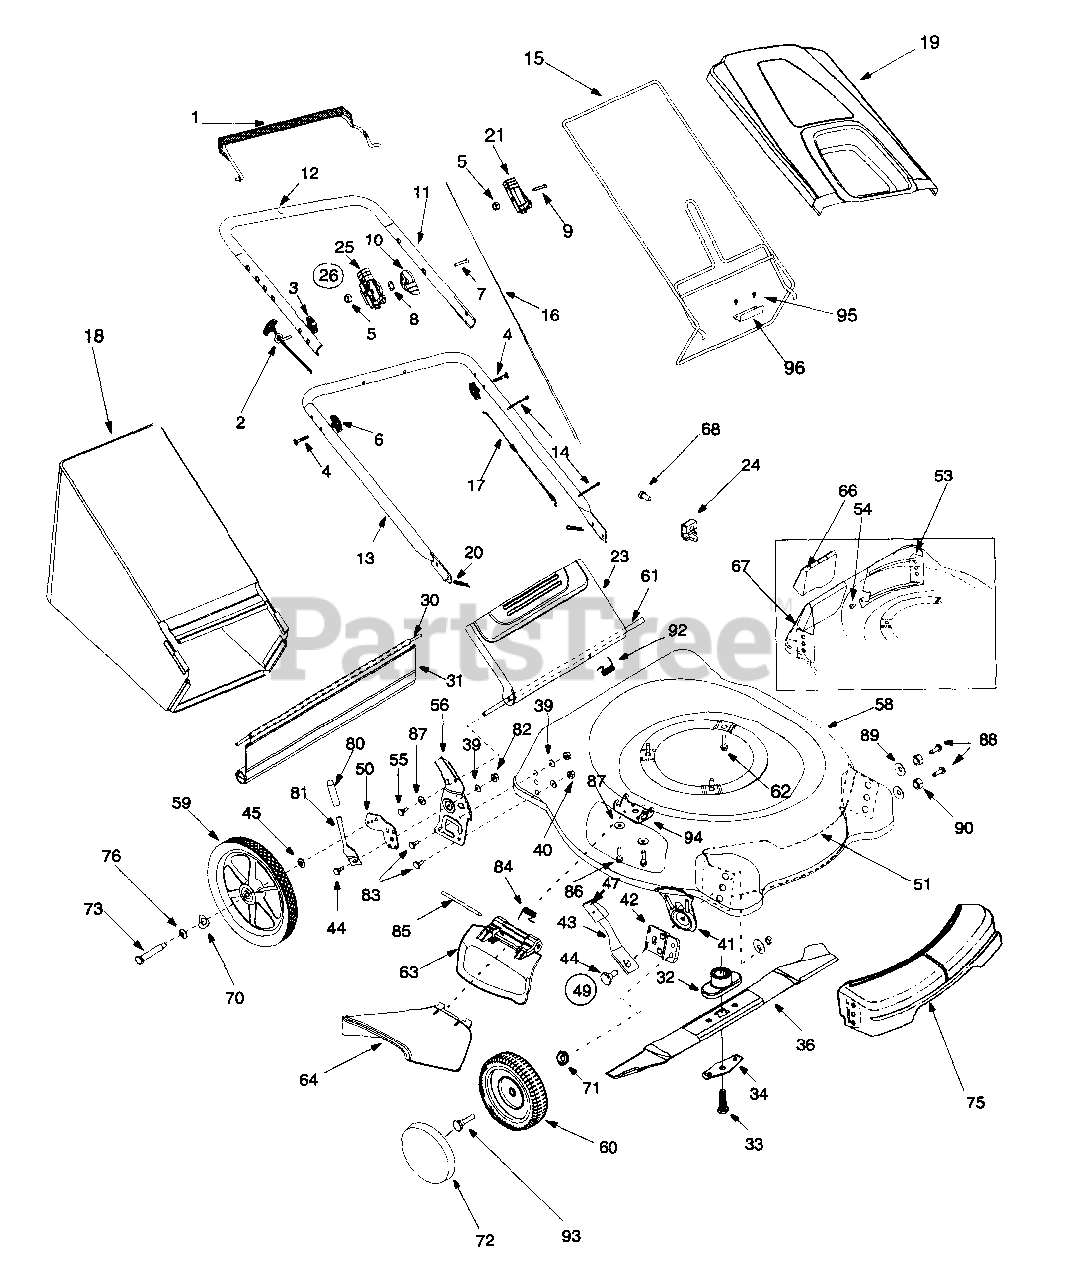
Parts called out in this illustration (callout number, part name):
2	Rope Guide
3	Handle Knob
4	Curved Hd. Bolt 5/16-18 x 2"
5	Hex L-Nut 1/4-20 Thd.
6	Hand Knob
7	Oval C-Sunk Screw
8	Spring Washer
9	Screw 1/4-20 x 1.31
10	Throttle Lever
14	Cable Tie
16	Control Cable - 39"
17	Throttle Cable - 60"
18	Grass Bag Ass'y w/o logo
19	Hard Top w/logo
20	Internal Cotter Pin
21	Throttle Housing w/o Lever
25	Throttle Body
26	Throttle Box Comp.
30	Wire Rod
31	Rear Flap
32	Blade Adapter Kit
33	Hex Bolt 3/8-24 x 1.5"
34	Blade Bell Support
36	Mulching Blade
39	Bell Washer .39" I.D. x 1.38"
40	Hex Nut 3/8-16 Thd.
41	Height Adj. Plate
43	Spring Lever: Front Wheel
44	Shoulder Bolt .5" Dia. x .357"
45	Bell Washer .38" I.D. x .68"
47	Spring Lever Knob
49	Height Adj. Assembly Comp - RH
50	Pivot Bar - RH
54	Torx Mach. AB-Tap Scr.
55	Hex Washer Screw 1/4-14 x .625
56	Handle Bracket Assembly - R.H.
60	Front Wheel Ass'y. 8 x 2
61	Chute Door Pivot Rod
62	Sems Screw TT 3/8-16 x 1
63	Mulching Plug (Hinged)
64	Chute Deflector
66	Rear Mulch Plug
68	Hex Washer Hd. Screw
70	Wave Washer
71	Spring Washer
72	Hub Cap Grey
73	Rear Axle Bolt
75	Front End Cover: Yellow
76	Flat Washer
80	Foam Grip
81	Height Adj. Lever
82	Hex Flange Lock Nut 3/8-16
84	Torsion Spring
85	Hinge Pin
86	Tapp Scr. 1/4-20 x .500
87	Bell Washer .265 x .75 x .062
88	Hex Screw 3/8-16 x .75
89	Bell Washer .39 x 1.13 x .062
90	Hex Nut 3/8-16
92	Torsion Spring
93	Front Axle Bolt
95	Hex Screw 1/4-14 x .625
